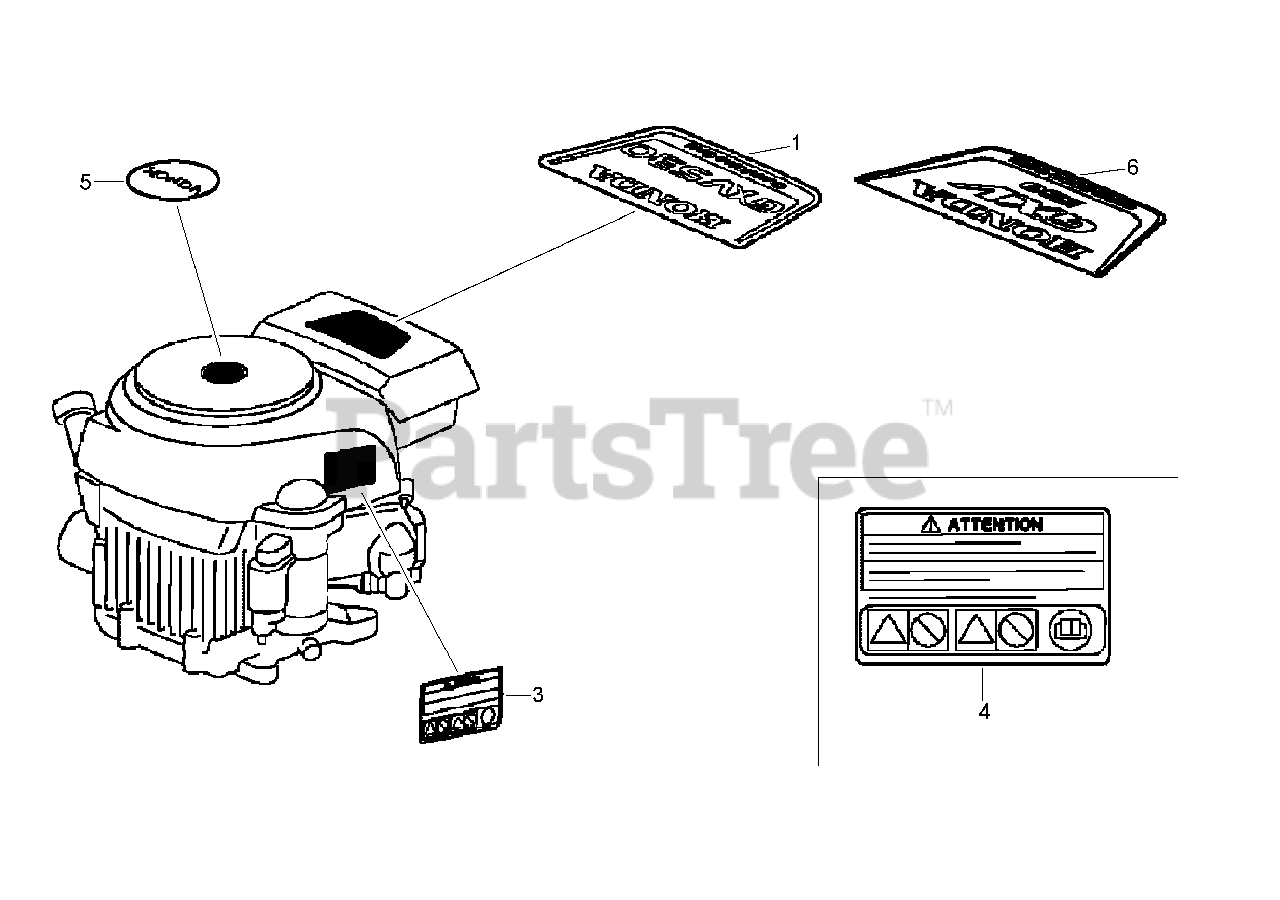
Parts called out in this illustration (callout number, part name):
1	MARK-EMBLEM (GXV530) (Up To Engine Serial No. 1006563)
3	MARK-OPERATOR CAUTION (ENGLISH) (MADE IN JAPAN)
3	MARK-OPERATOR CAUTION (PICTOGRAPH) (MADE IN JAPAN)
4	MARK-OPERATOR CAUTION (FRENCH) (MADE IN JAPAN)
5	MARK-HONDA
6	MARK-EMBLEM (GXV530) (From Engine Serial No. 1006564)
